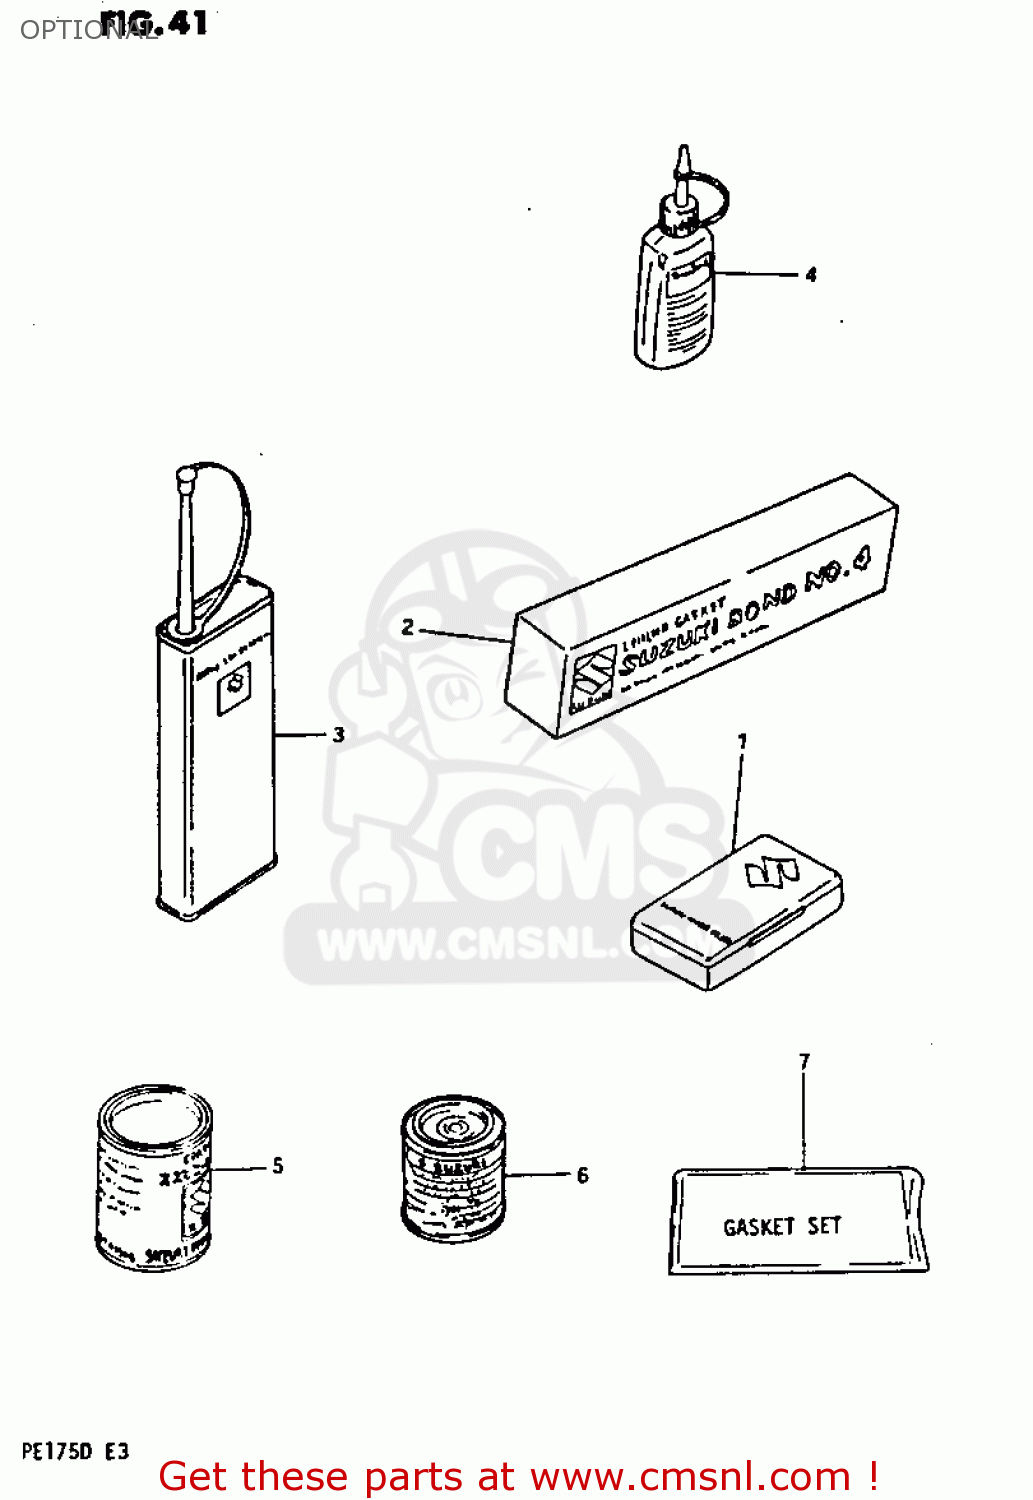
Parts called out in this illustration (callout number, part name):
1	TUBE REPARING TOOL
2	LIQUID GASKET 1
3	THREAD LOCK NO.1401 CLEAR 200G
4	THREAD LOCK NO
5	GREASE(C)EP2 LITHIUM 150G
6	PAINT,BLACK
7	GASKET SET
